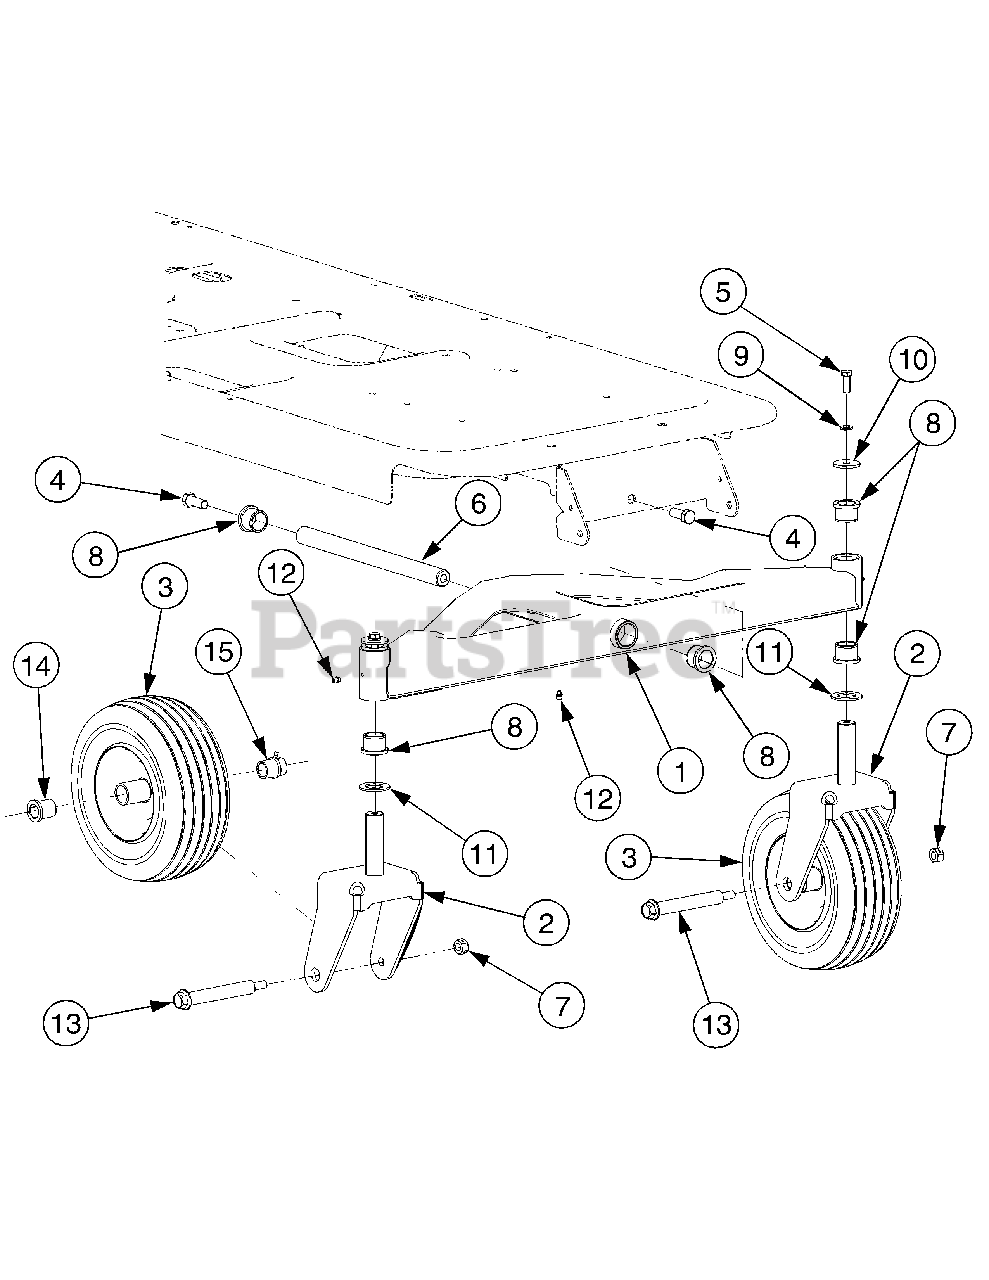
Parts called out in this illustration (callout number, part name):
3	Wheel Assembly, 11.0 x 4.0 x 5.0
4	Screw, Hex Lock, 1/2-13 x 1.25 GR5
5	Screw, Hex Cap, 3/8-16 x 1.0 GR5
6	Shaft, Axle
7	Nut, Hex Lock, 1/2-13 GRB
8	Bearing, Flange, 1.0 x 1.246
9	Washer, Lock, 3/8
10	Washer, Flat, .39 x 1.5 x .134
11	Washer, Flat, 1.0 x 1.75 x .107
12	Fitting, Lube, 3/16 Drive
13	Screw, Shoulder, .75 x 4.75:7/16-14
14	Bearing, Flange, .76 x 1.0 x 1.2
15	Bearing, Flange, .76 ID w/Lube Ftg.
